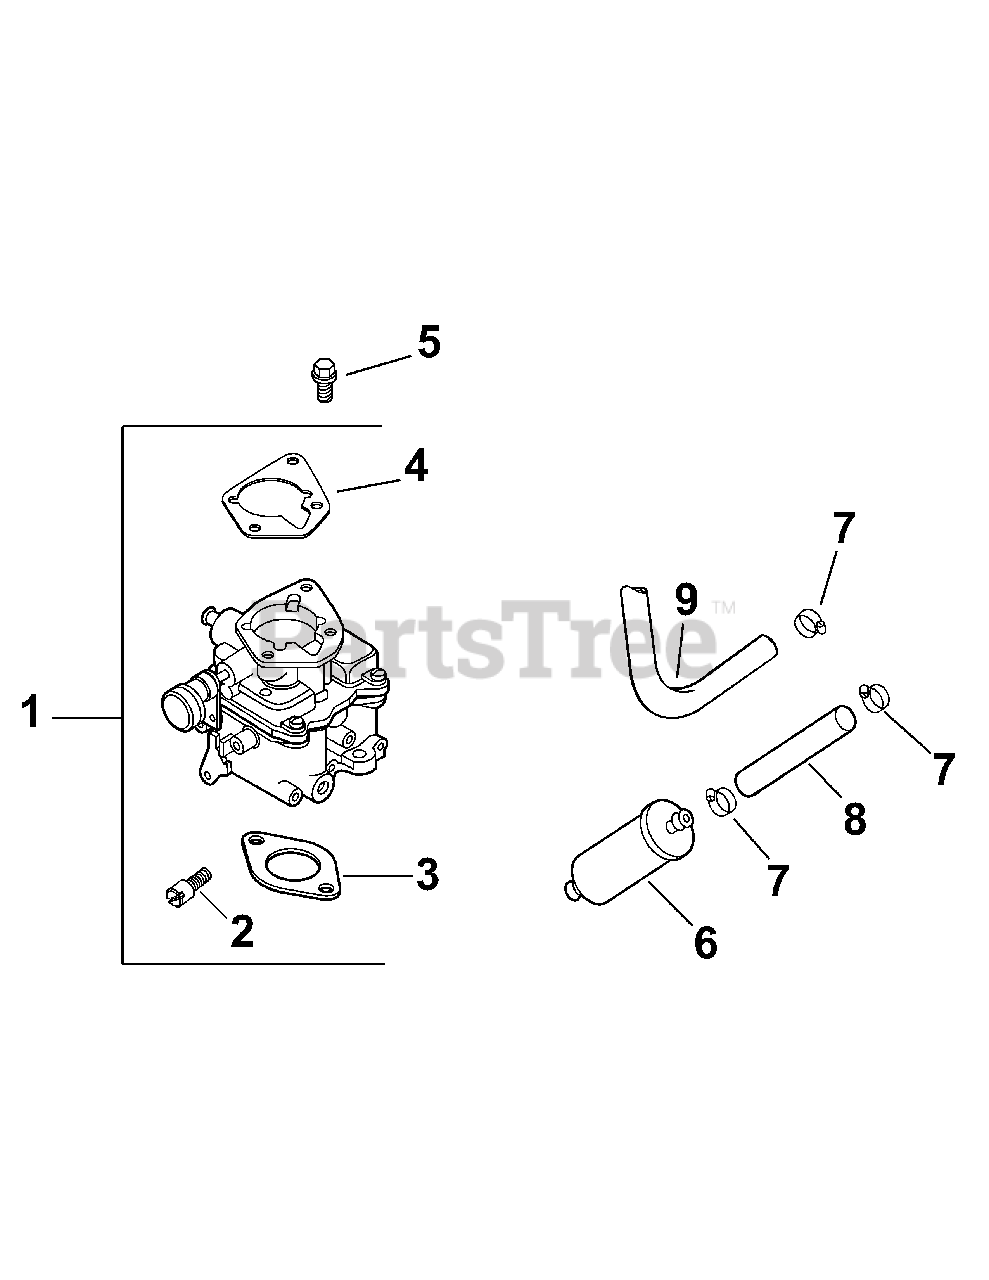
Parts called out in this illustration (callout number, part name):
1	Kit, carburetor w/gasket (Includes 2-4)
2	Screw, throttle stop
3	Gasket, air cleaner base
4	Gasket, carburetor
5	Screw, hex. flange M6x1.0x25 (2)
6	Filter, fuel
7	Clamp, hose (4)
8	Line, fuel 21" (carb to filter)
9	Line, fuel 11" (carb to pump)
